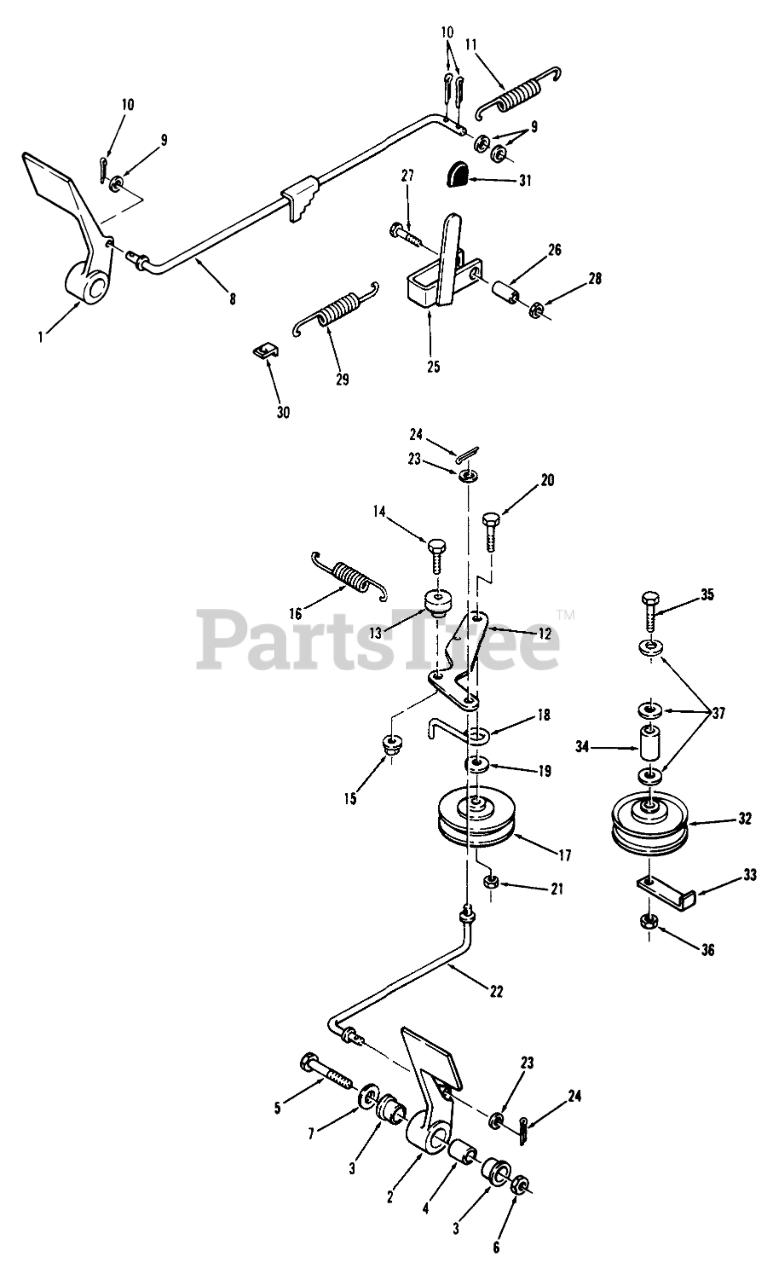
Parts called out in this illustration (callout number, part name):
1	PEDAL-BRAKE R
2	Clutch Pedal
3	BUSHING
4	Spacer
5	H H C S
6	Eslok Nut
7	Washer
8	Brake Rod
9	WASHER 5/16 NYLON
10	Pop Rivet
11	SPRING-EXTENSION
12	Clutch Lever
13	SPACER-CLUTCH LINK
14	BOLT
15	LOCKNUT-FLANGE
16	SPRING-EXTENSION
17	PULLEY-IDLER STATION
18	RETAINER-BELT
19	Washer
20	Bolt
21	Nut
22	Assy-Rod Clutch
23	WASHER-NYLON
24	Pop Rivet
25	Assy-Brake Lever
26	SPACER
27	Carriage Bolt
28	LOCKNUT-FLANGE
29	SPRING-EXTENSION
30	CLIP - SPRING
31	GRIP
32	Idler Pulley
33	Belt Retainer
34	Spacer
35	Bolt
36	Nut
37	Washer
